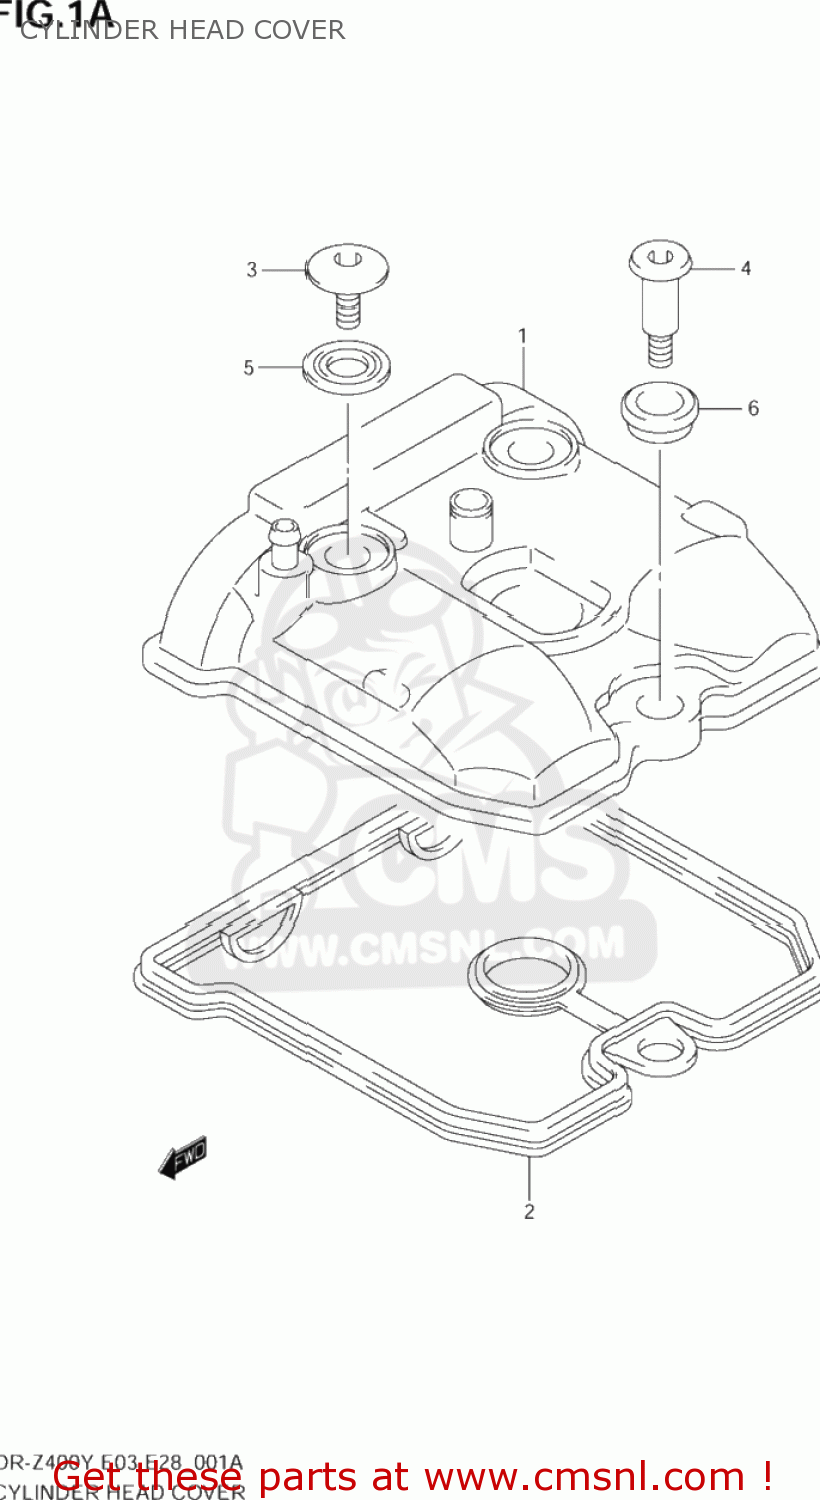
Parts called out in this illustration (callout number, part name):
1	COVER,CYLINDER HEAD
2	GASKET,CYL HEAD COVER (NAS)
3	BOLT(7X17.5)
4	BOLT(7X31)
5	WASHER(10.6X25.5X2.3)
6	CUSHION,HEAD COVER BOLT
